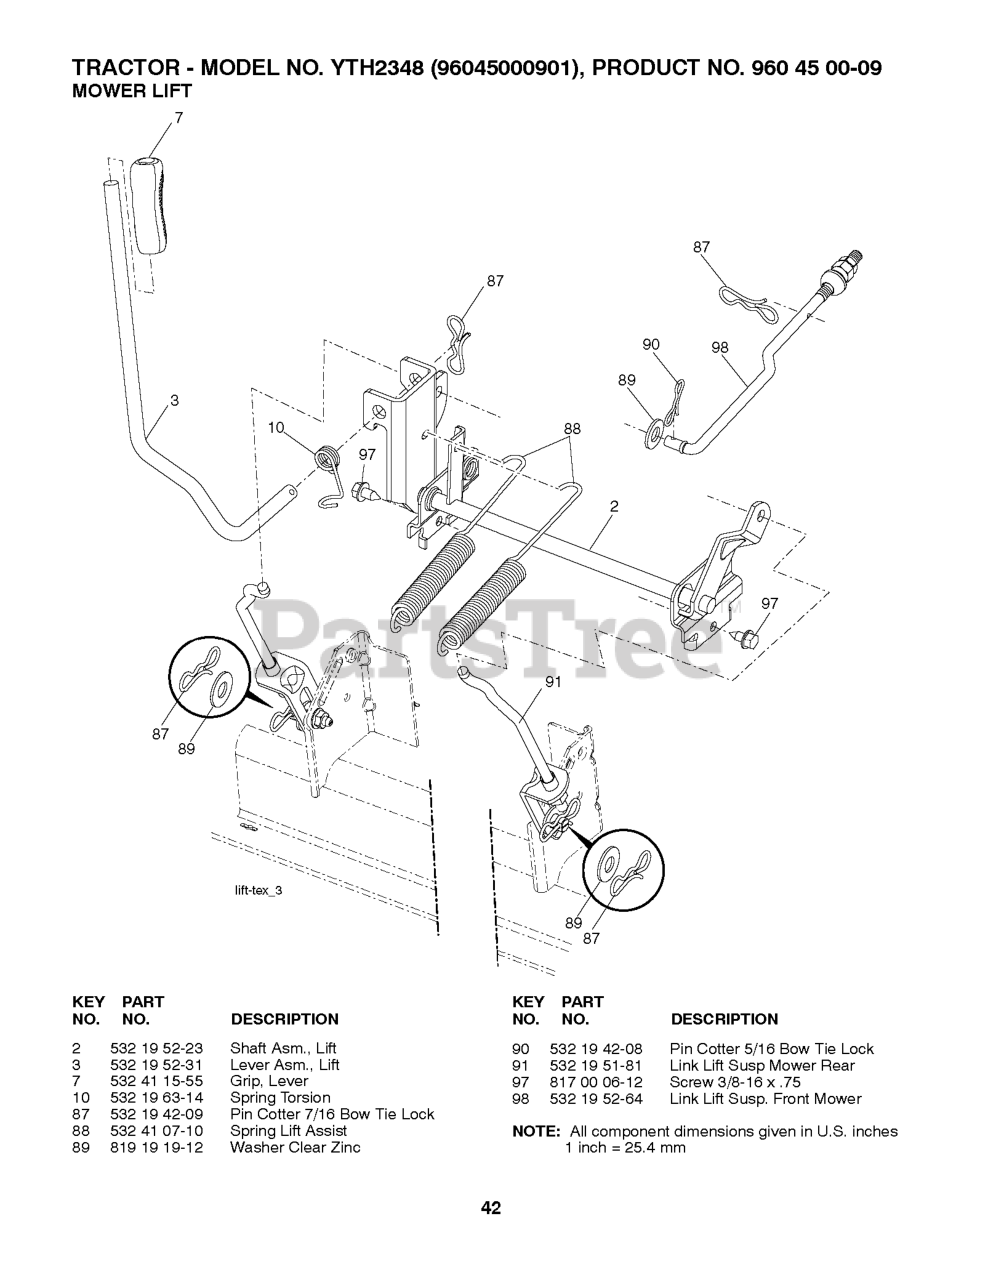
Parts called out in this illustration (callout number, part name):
2	SHAFT.ASM.LIFT.CROSS.H
3	LEVER.LIFT.HANDLE.LT
7	GRIP.HANDLE.LIFT.PVC.BLACK
10	SPRING.TORSION.LIFT.HANDLE
87	PIN.COTTER.7/16.BOW TI.
88	SPRING.LIFT.ASSIST
89	WASHER.CLEAR.ZINC
90	PIN.COTTER.5/16.BOW TI
91	LINK.ASM.LIFT.REAR
97	SCREW, 3/8-16X3/4
98	LINK.ASM.SUSP.FRONT.MWR.10.5
